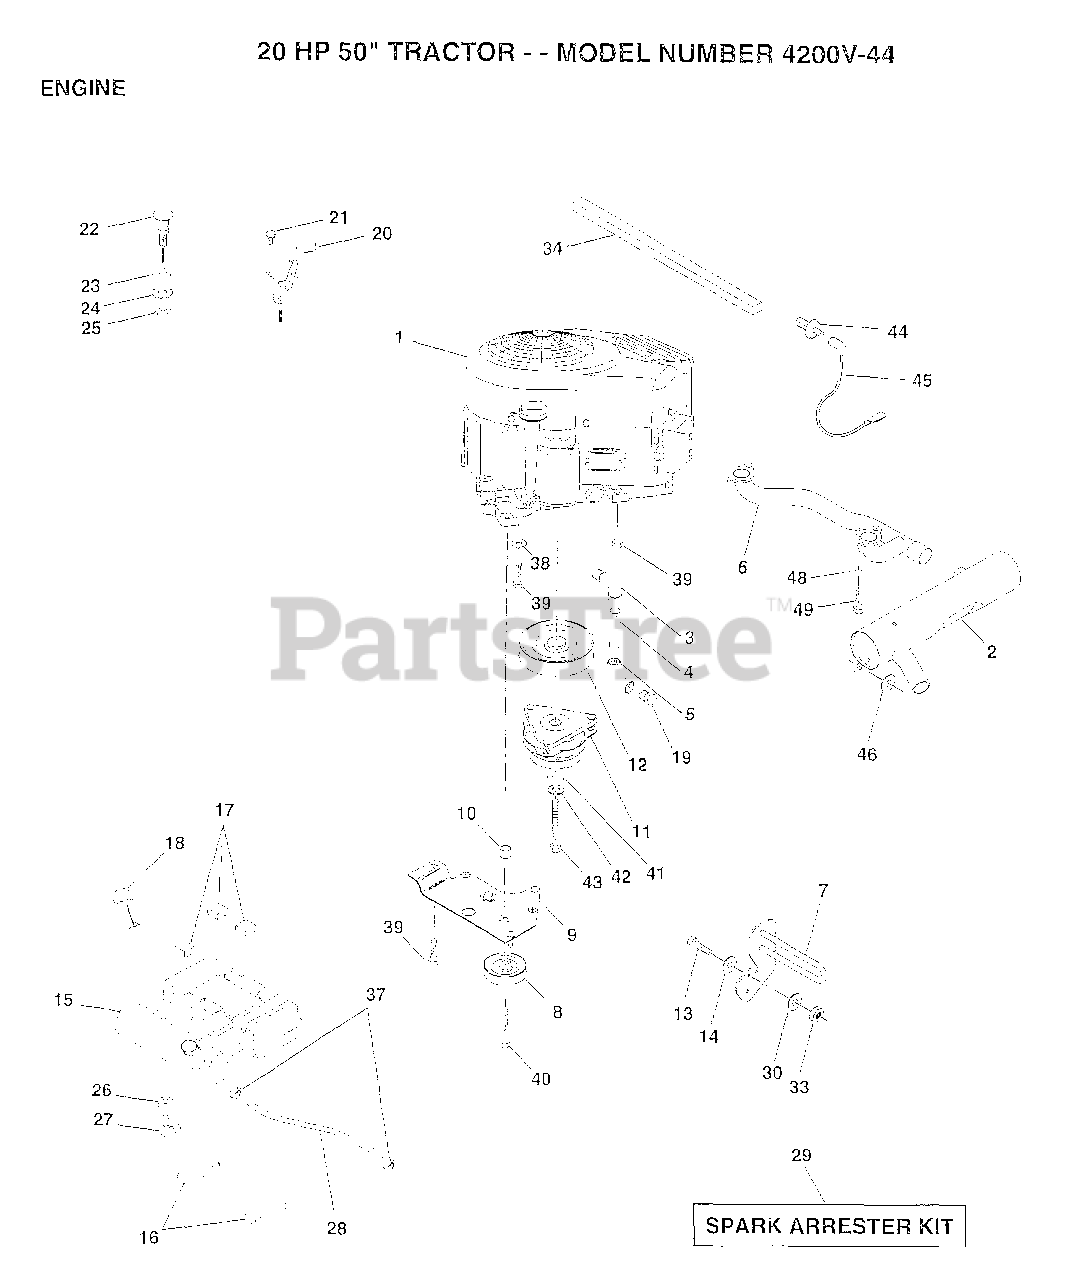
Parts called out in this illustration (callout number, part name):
3	STREET ELBOW LT
4	PIPE NIPPLE
5	ELBOW
6	PIPE.EXHAUST.B&S
10	BUSHING.
12	PULLEY.ENGINE.VGT
13	"BOLT,HEX"
14	WASHER
16	PAD IDLER TI
17	PAD-SPACER LT
18	CAP ASM FUEL
19	PLUG T
21	SCREW LT
23	WASHER
24	LOCKWASHER
26	BUSHING OUTLET T
27	STEM.TANK.FUEL
29	SPARK ARREST KIT
30	WASHER T
32	SCREW LT
33	NUT
34	FOAM-STRIP LT
35	LOCKWASHER
36	SCREW
37	HOSE CLAMP
38	LOCKWASHER
39	SCREW LT
40	SCREW.3/8-16X3.25
41	WASHER
42	LOCKWASHER
44	SWITCH OIL KOHLER
45	WIRE.LEAD.SENTRY
46	WASHER HYT
48	LOCKWASHER
49	BOLT.HD.SOCKET.
